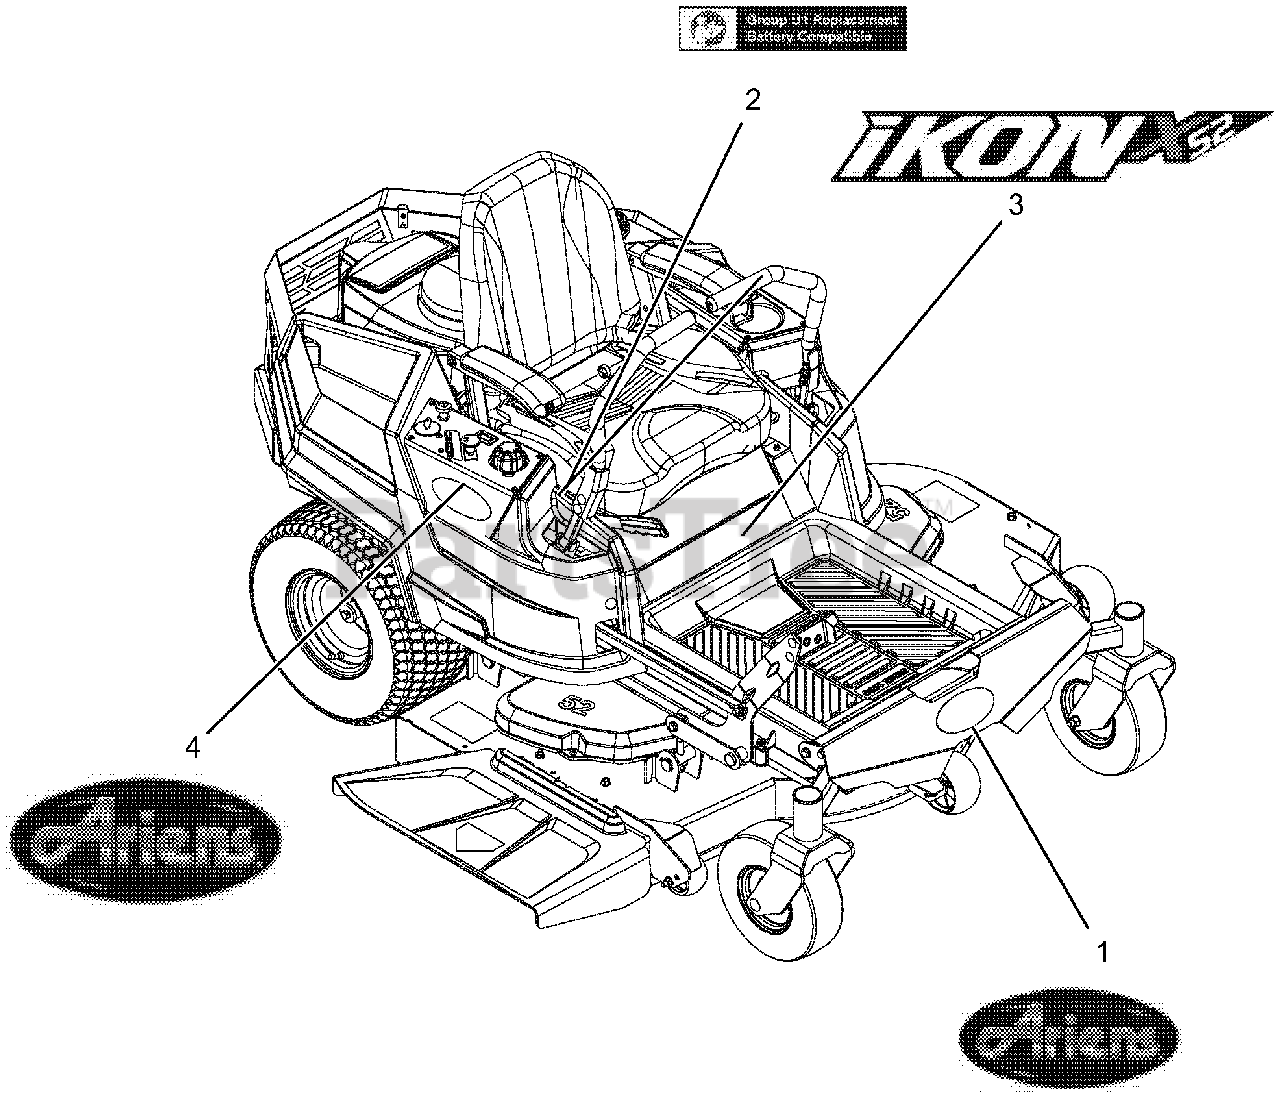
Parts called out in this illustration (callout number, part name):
1	DECAL, ARIENS JEWEL
2	DECAL, U1 BATTERY REPLACEMENT
3	DECAL, ARIENS IKON 52
4	DECAL, ARIENS JEWEL (LARGE)
